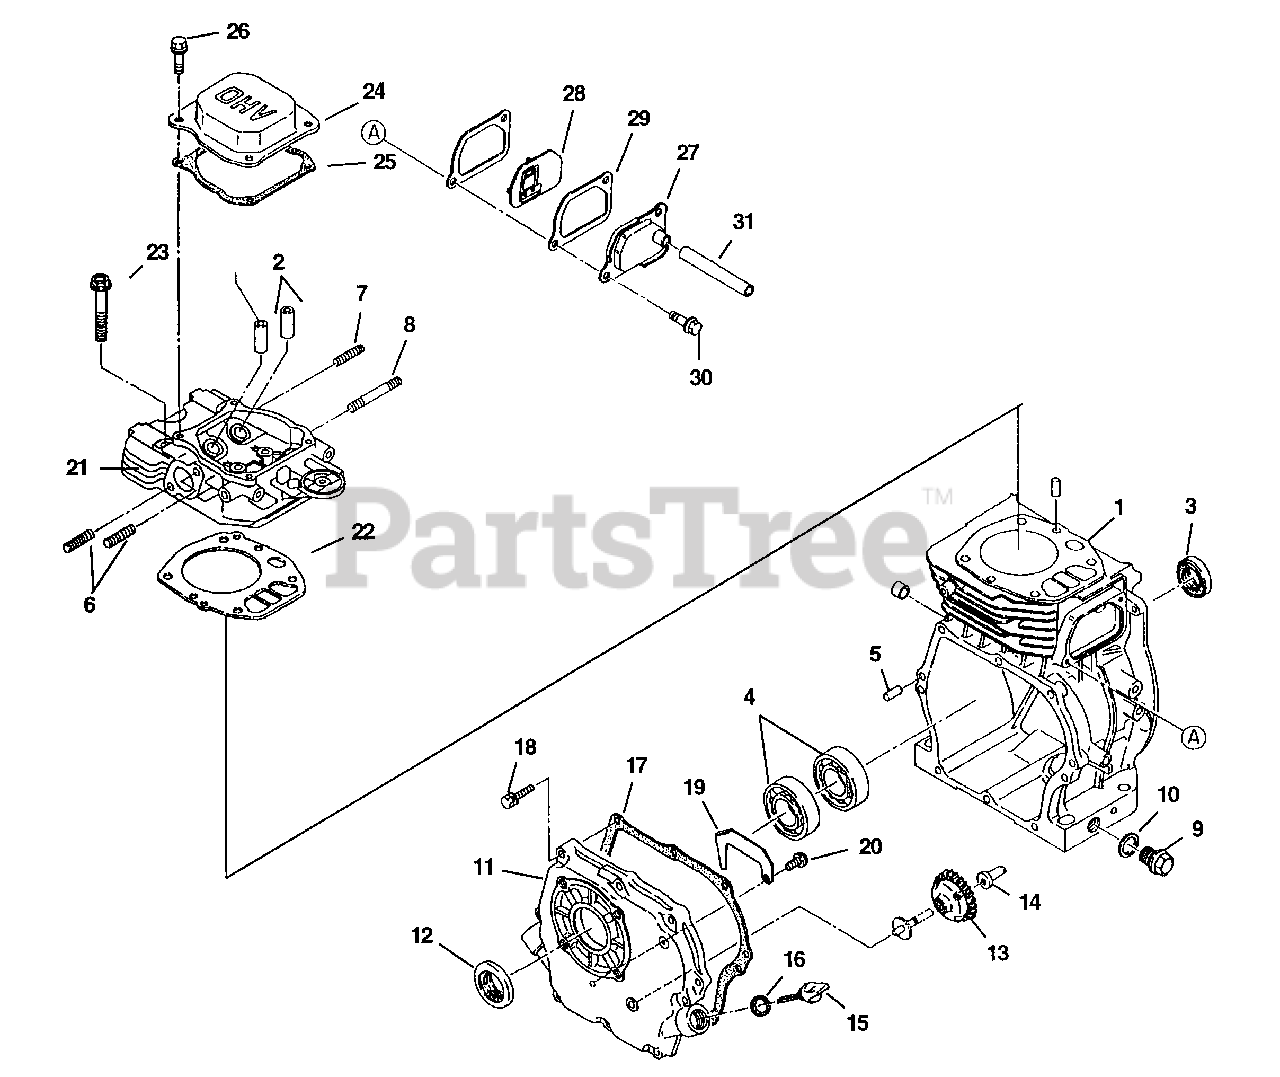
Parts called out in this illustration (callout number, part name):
1	Crankcase
2	Valve guide
3	Oil seal
4	Ball bearing
5	Dowel pin
6	Stud M8 X 1.25 X 30L
11	Main bearing cover
12	Oil seal
13	Governor gear
14	Governor sleeve
15	Oil gauge
17	Bearing cover gasket
18	Bolt & washer
19	Sheltor plate
20	Screw & washer
21	Cylinder head
22	Head gasket
23	Flange bolt
24	Rocker cover
25	Rocker cover gasket
26	Flange bolt M6 X 1.0 X 12L
27	Breather cover
28	Breather plate
29	Breather cover gasket
30	Flange bolt M6 X 1.0 X 14L
31	Rubber pipe
